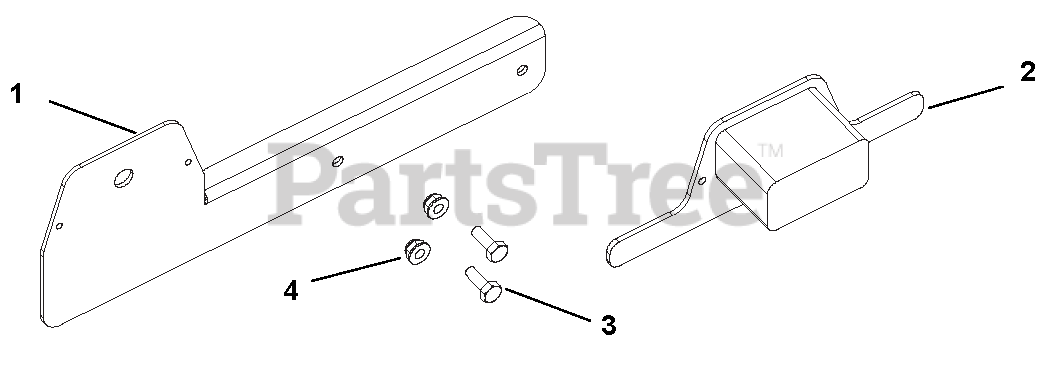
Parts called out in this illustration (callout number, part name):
1	BRKT, SPLITTER LICENSE PLATE
2	LICENSE PLATE BRACKET W/ LIGHT
3	@BLT-HEX .25-20X.75 GR5 YWZC
4	@NUT-LK-NYL-FLG .25-20 YWZC
